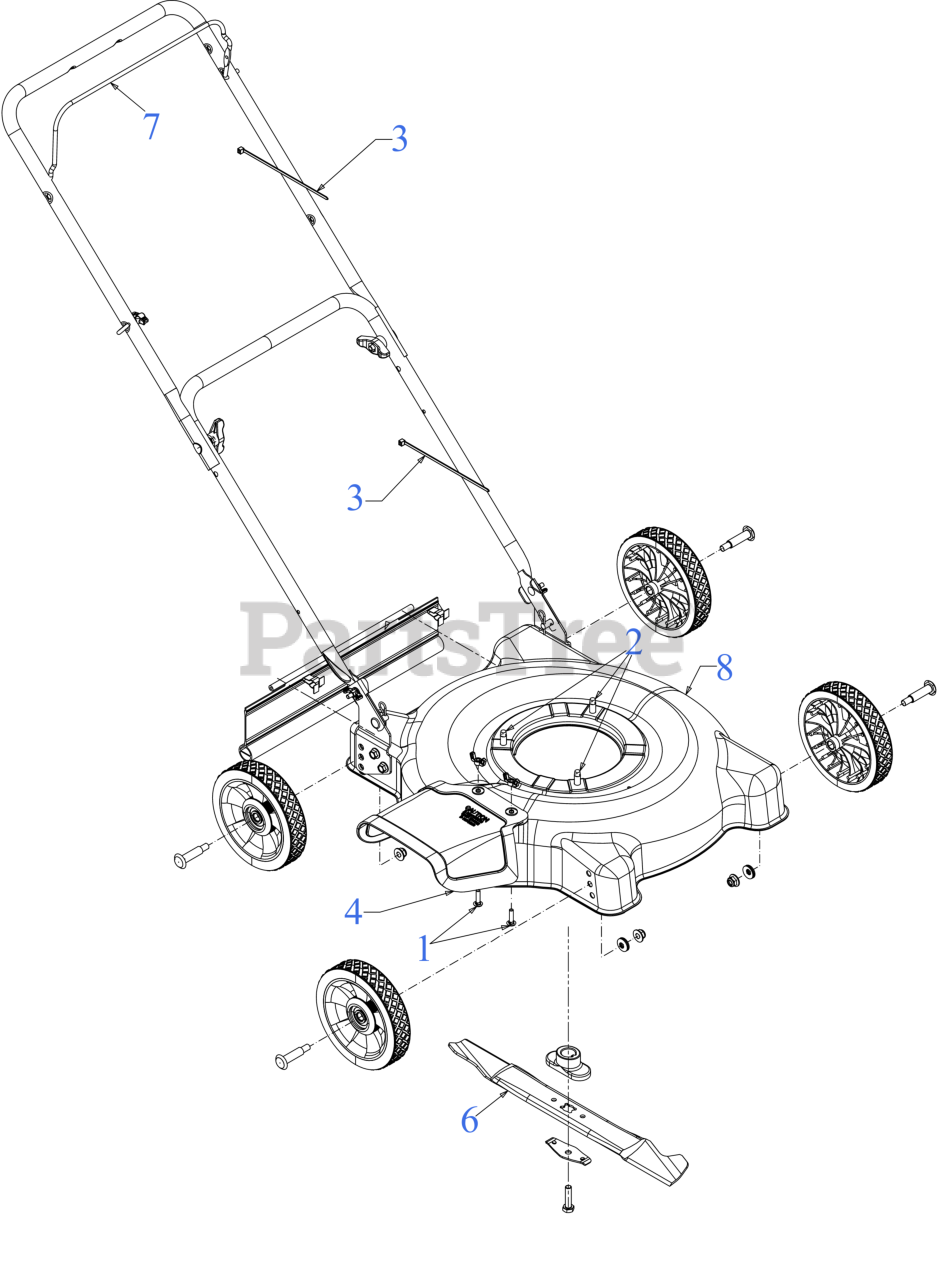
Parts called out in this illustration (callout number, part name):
1	SCREWPACK ASSEMBLY
2	SCREW 3/8-16 x 1
3	7" CABLE TIE
4	20" FIXED DISCHARGE CHUTE
6	20" BLADE
6	Genuine Factory Parts 20" MULCHING BLADE (STAR)
7	OPERATOR BAIL
